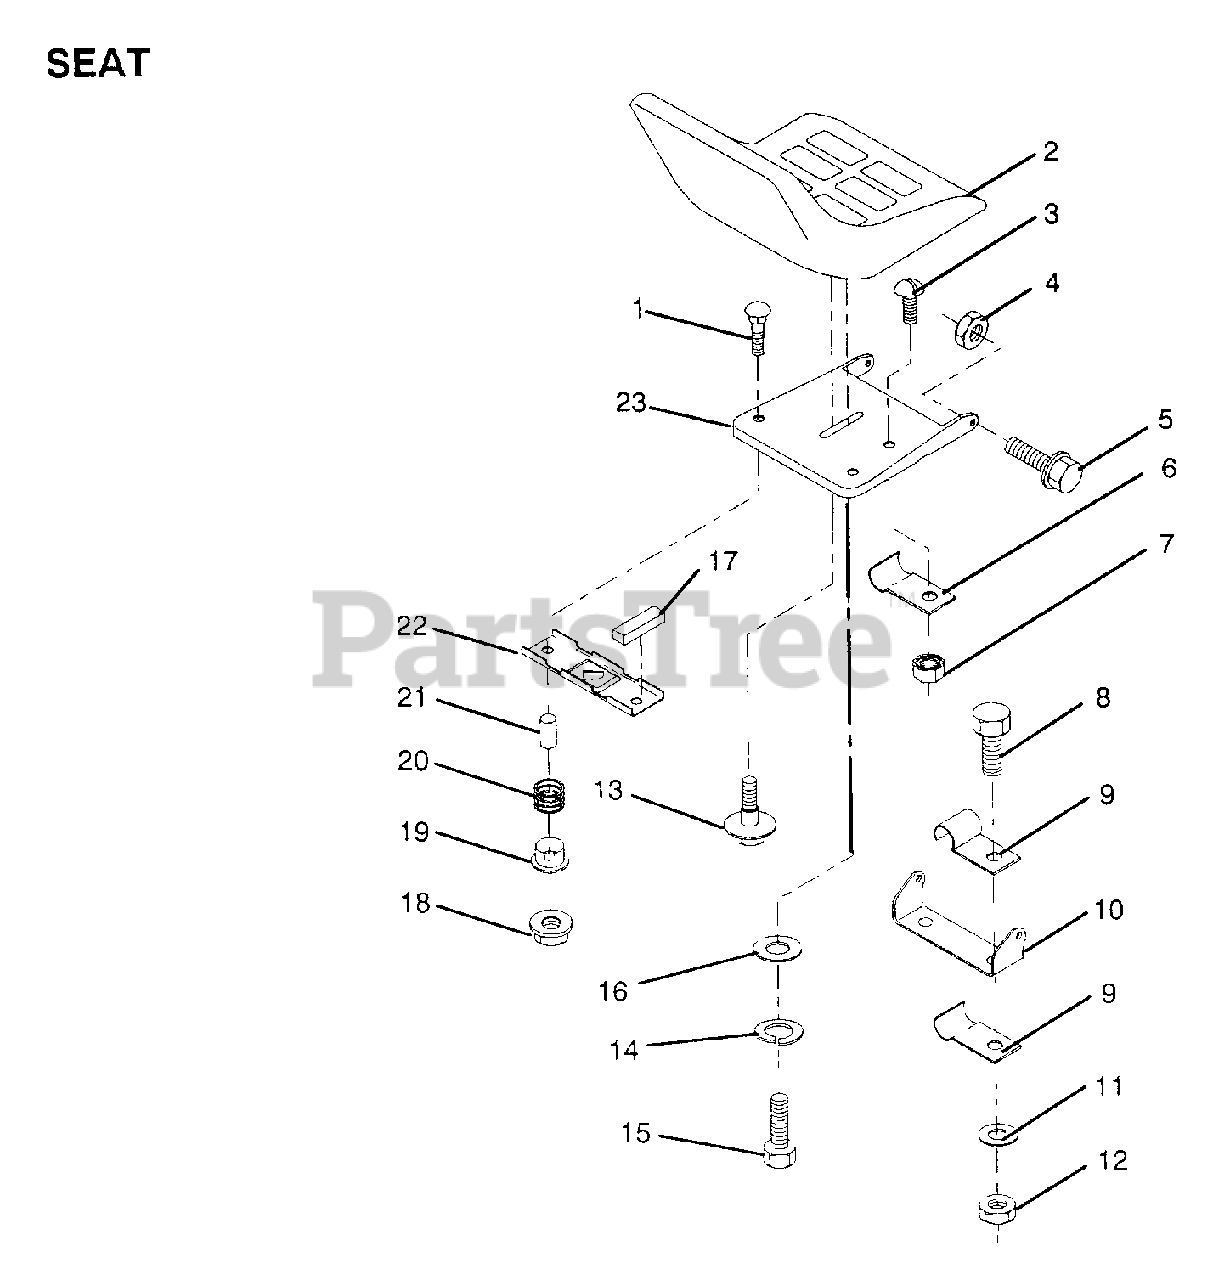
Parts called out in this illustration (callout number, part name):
1	BOLT
7	"NUT,KEPS"
9	"CLIP,INSULATOR"
11	WASHER
13	"BOLT,SHOULDER"
14	LOCKWASHER
15	BOLT
16	WASHER
17	STRIP FORM
19	BUSHING
20	SPRING
21	SPACER SPLIT
22	BRKT SWITCH
